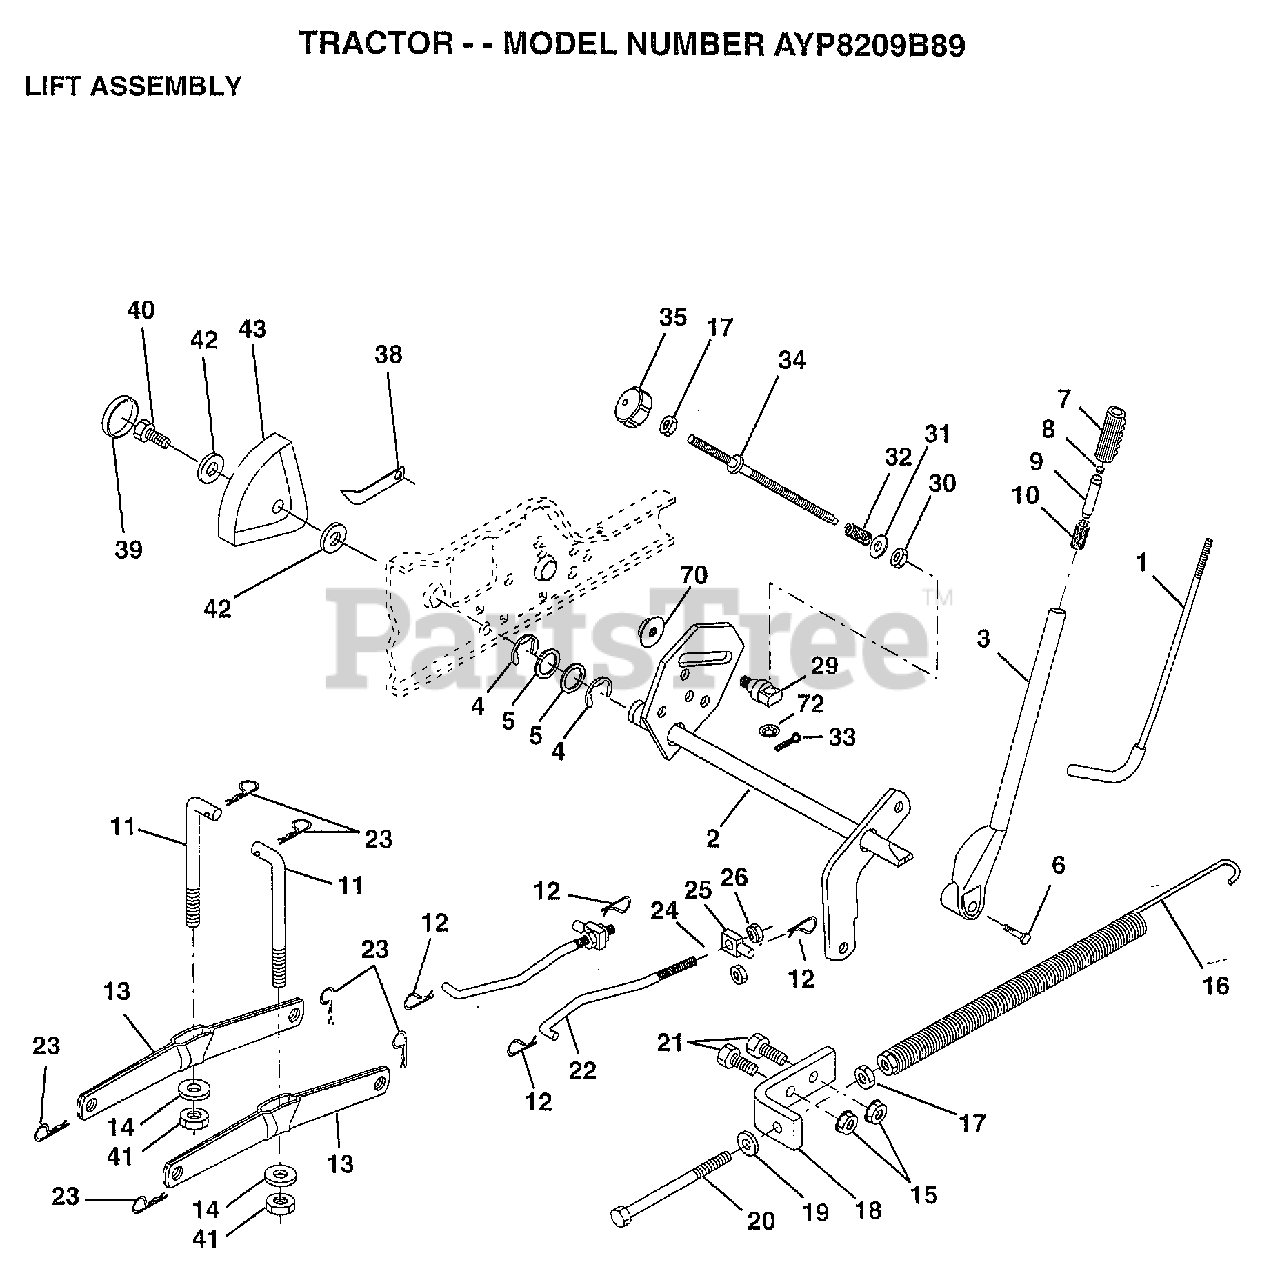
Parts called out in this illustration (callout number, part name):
1	LEVER ROD LT
2	SHAFT.ASM.LIFT.VGT
3	LEVER.ASM.LIFT.RH
4	E-RING
5	WASHER
6	"BOLT,HEX"
7	GRIP HANDLE
10	SPRING T
11	LINK.LIFT.MWR.VGT
12	RETAINER SPRING
13	ARM SUSP REAR
14	BEARING PVT LH
17	NUT
18	BRACKET SPRING AS
19	WASHER
20	BOLT-ADJ SPRING T
21	BOLT
22	LINK.FRONT
24	NUT
25	TRUNION
26	NUT.LK.W/WSH.1/2.
29	TRUNNION
30	NUT T
31	WASHER
32	SPRING.COMP.INF.H
34	ROD.ADJ.LIFT
35	KNOB INF 3/8-16
38	POINTER-INDICAT
39	"PLUG,HOLE"
40	SCREW
41	NUT.CROWNLOCK.3/8
42	WASHER
43	HEIGHT INDICATOR
70	NUT.HXFLG.LOCK.
